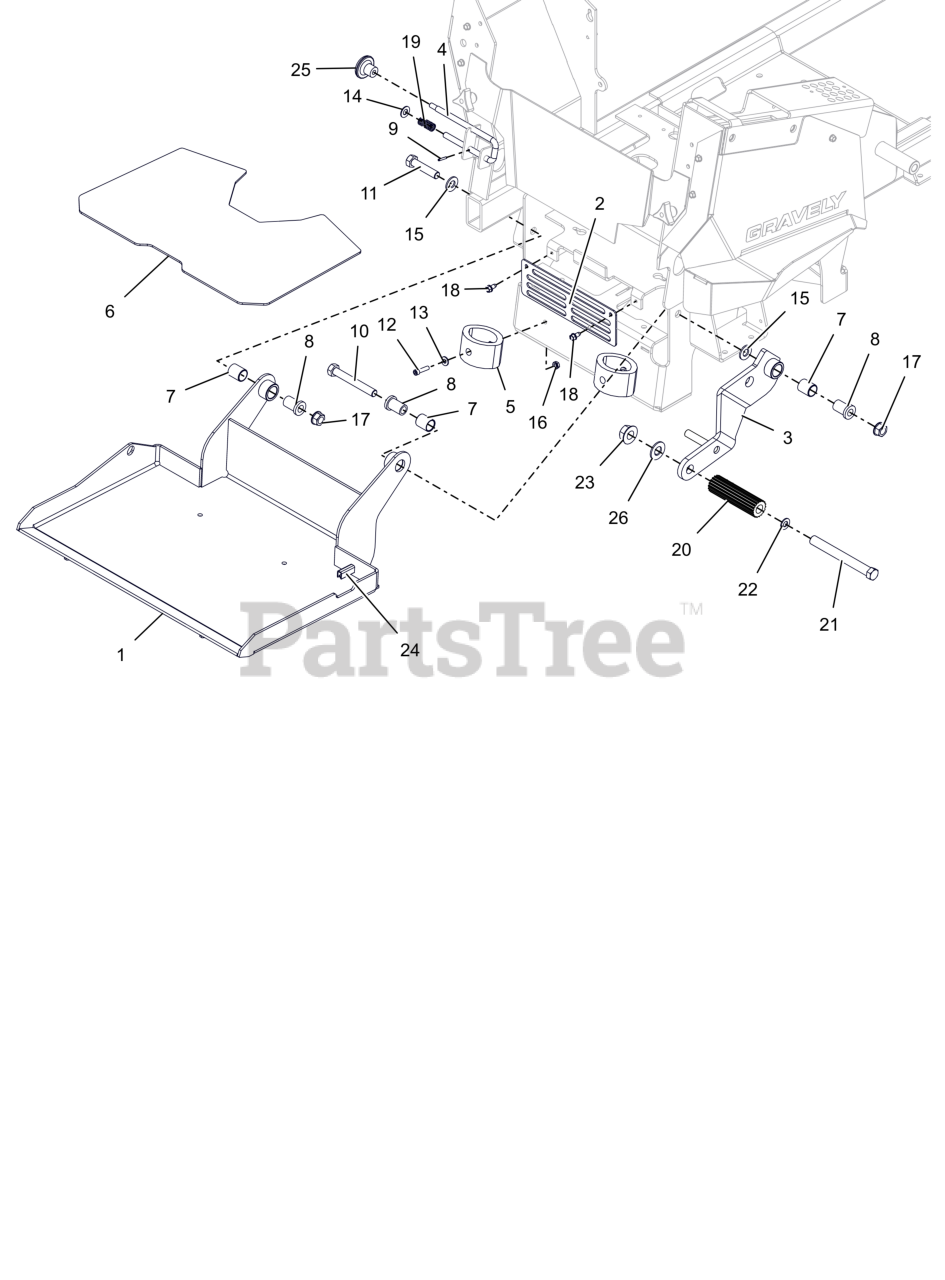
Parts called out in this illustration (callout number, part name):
1	PLATFORM, 32-36" OPERATOR (BLACK)
2	GUARD, FOOT (RED)
3	WLDMT, DECK LIFT FOOT ASSIST (BLACK)
4	PIN, PLATFORM LOCK
5	BUMPER, PLATFORM
6	TAPE, OPERATOR PLATFORM GRIP
7	BRG, .750 X .875 X 1.000
8	BSHG-FLG .515X.746X1.290X1.000
9	PIN-ROLL .125X.75
10	BLT,HEX .50-13X3.75 G5 ZCC
11	BLT, HEX .50-13X2.25 G5 ZCC
12	SCR, SKH .25-20X1.00
13	WSHR,FLT .281X.625X.065 ZCC
14	WSHR-FL-STL 0.406X0.812X0.055 HRD
15	WSHR,FLT .531X1.062X.095 ZCC
16	NUT-KEPS .250-20 ZCC
17	NUT-LK-CTR-FLG .500-13 GG ZCC
18	SCR-TAP .25-20X.50 HWH ZCC
19	SPRING, COMPRESSION
20	ROD, FOOT PEDAL (BLACK)
21	BLT, HEX .62-11X5.50 G5 FBP
22	WSHR,FLT .406X.812X.065 ZCC
23	NUT,FLG-TOP LK .625-11 FBP
24	STRIP, COWL
25	KNOB, PUSH-PULL .312-18
26	WSHRFLT 5/8SAE CARBHARD FBP
